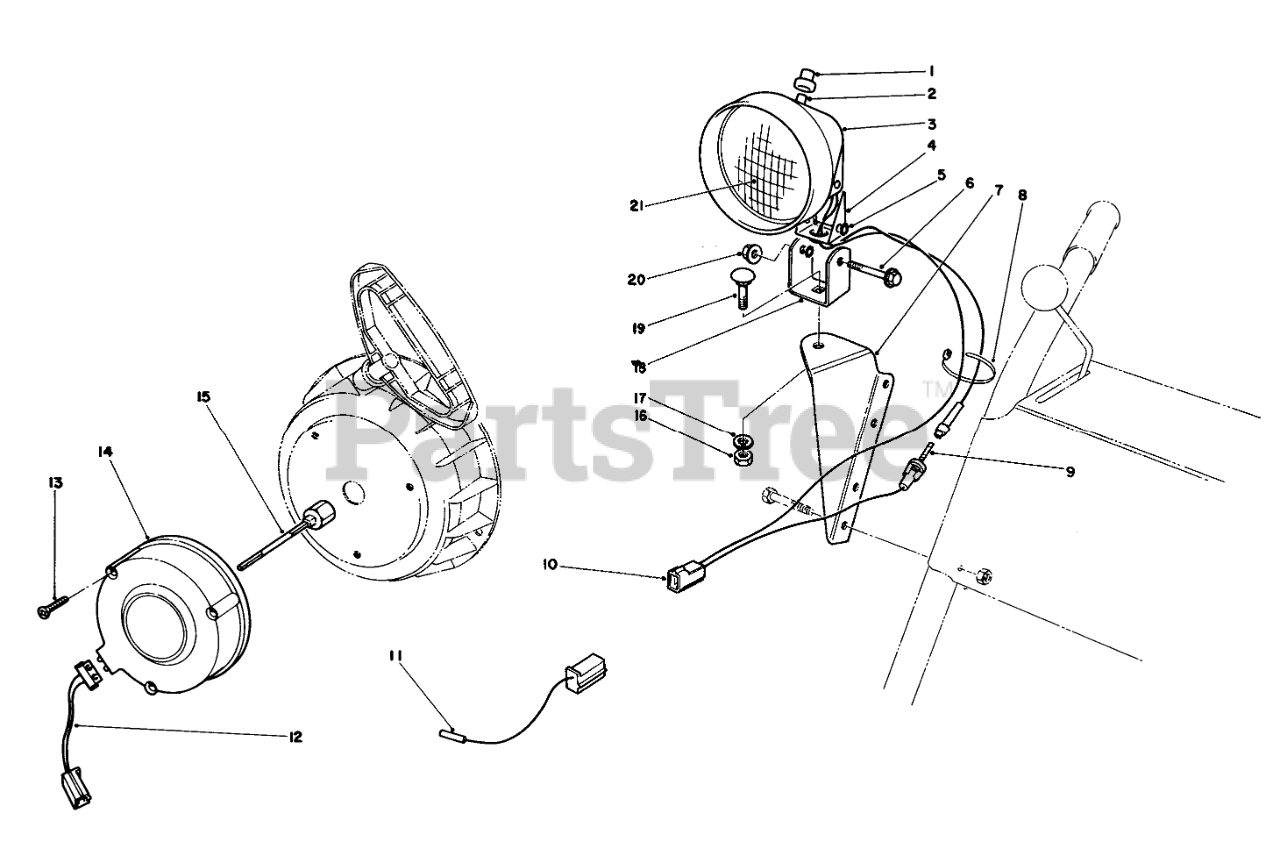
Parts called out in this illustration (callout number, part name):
1	BOOT-SWITCH
2	SWITCH ASM
3	Bucket-Headlamp
4	TO BE DISCONTINED-NOT NEEDED ON PRODUCT
5	WASHER-LOCK
6	SCREW-HH
7	LAMP MOUNT B
8	TIE-CABLE
9	Fuse-7 1/2 Amp
10	WIRE ASM
11	WIRE ASM
12	Connector-Wire
13	SELF TAP SCREW
14	Alternator
15	Shaft-Alternator, 3 Inch
16	NUT-HEX
17	WASHER-LOCK
18	BRACKET
19	BOLT-CARR
20	NUT-HF
21	SEALED BEAM
